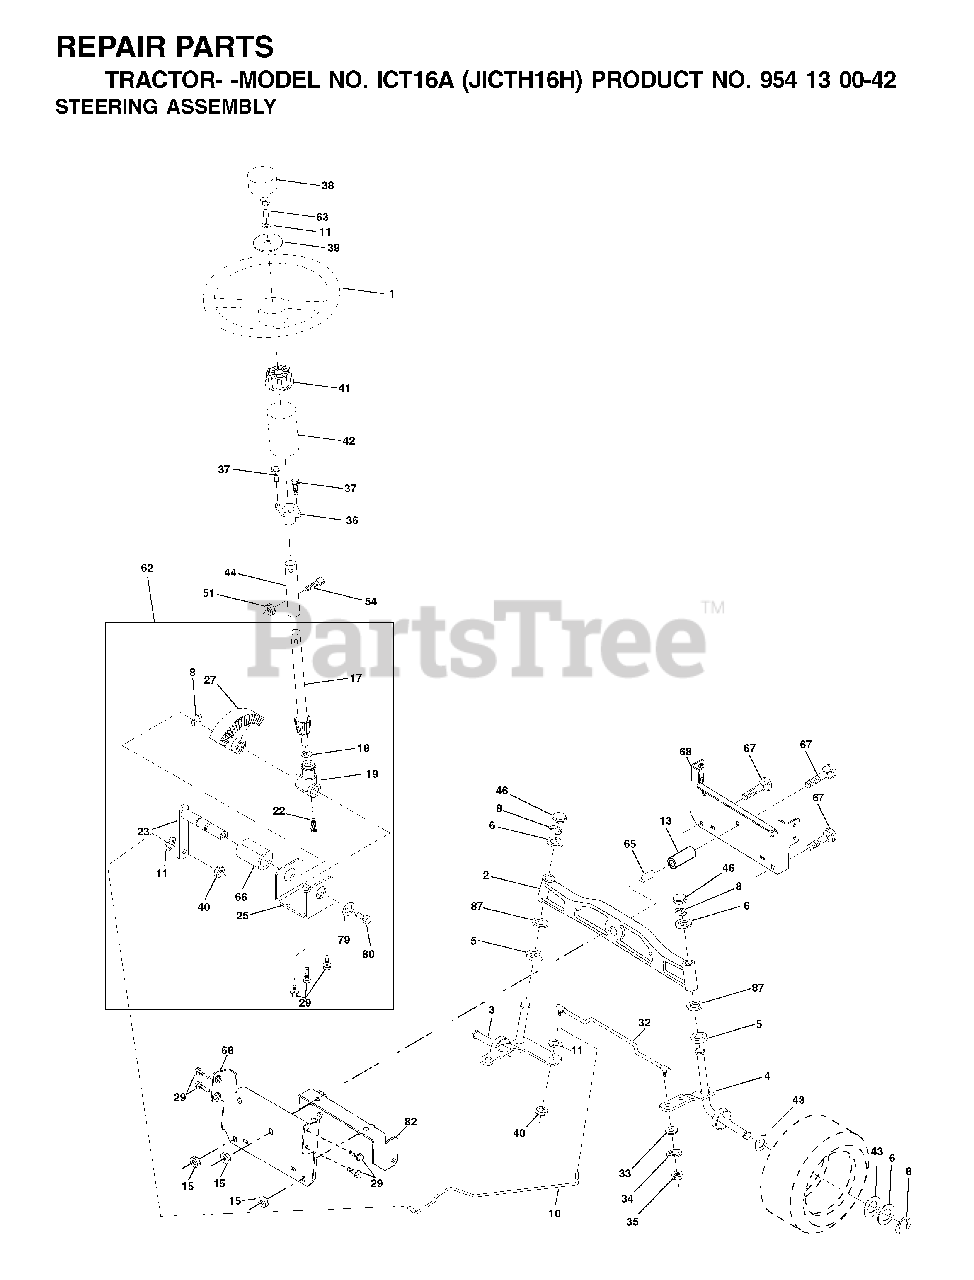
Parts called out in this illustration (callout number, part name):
2	AXLE ASM
3	SPINDLE.ASM.LH.15"TIRES
4	SPINDLE.ASM.RH.15"TIRES
8	RING CLIP
10	DRAGLINK.15".TIRES
11	WASHER, LOCK 3/8
13	TUBE, PIVOT AXLE
15	NUT
17	SHAFT ASM STEERING
18	THRUST WASHER
19	STEERING SHAFT SUPPORT
22	SCREW.HX.WSH.HD
23	SHAFT ASSY PITTMAN
25	BRACKET STEERING
27	GEAR.SECTOR
29	SCREW 3/8-16X3/4
32	ROD.ASM.TIE.BALL.JOINT.NOVAN
33	WASHER M
34	LOCKWASHER
35	NUT, CROWNLOCK
36	BUSHING, STEERING
39	WASHER 13/32 X 2-3/8 X 12 GA
40	GRIPCO NUT
41	STEERING WHEEL ADAPTOR
42	BOOT.STEERING.SHAFT.BLACK
44	EXT SHAFT STEERING
46	CAP.SPINDLE
51	NUT.71038.31-18.HEX.NYLOCK
54	BOLT.5/16-18X1-1/4 FULL.THREAD
62	STEERING KIT
65	SPACER BRACE AXLE
66	BEARING ARM
67	BOLT
68	BRACE.AXLE.15"TIRES
80	BOLT.HX.NYLON3/8-16X
82	BRACKET
87	WASHER, FLAT .781 X 1 1/2"
